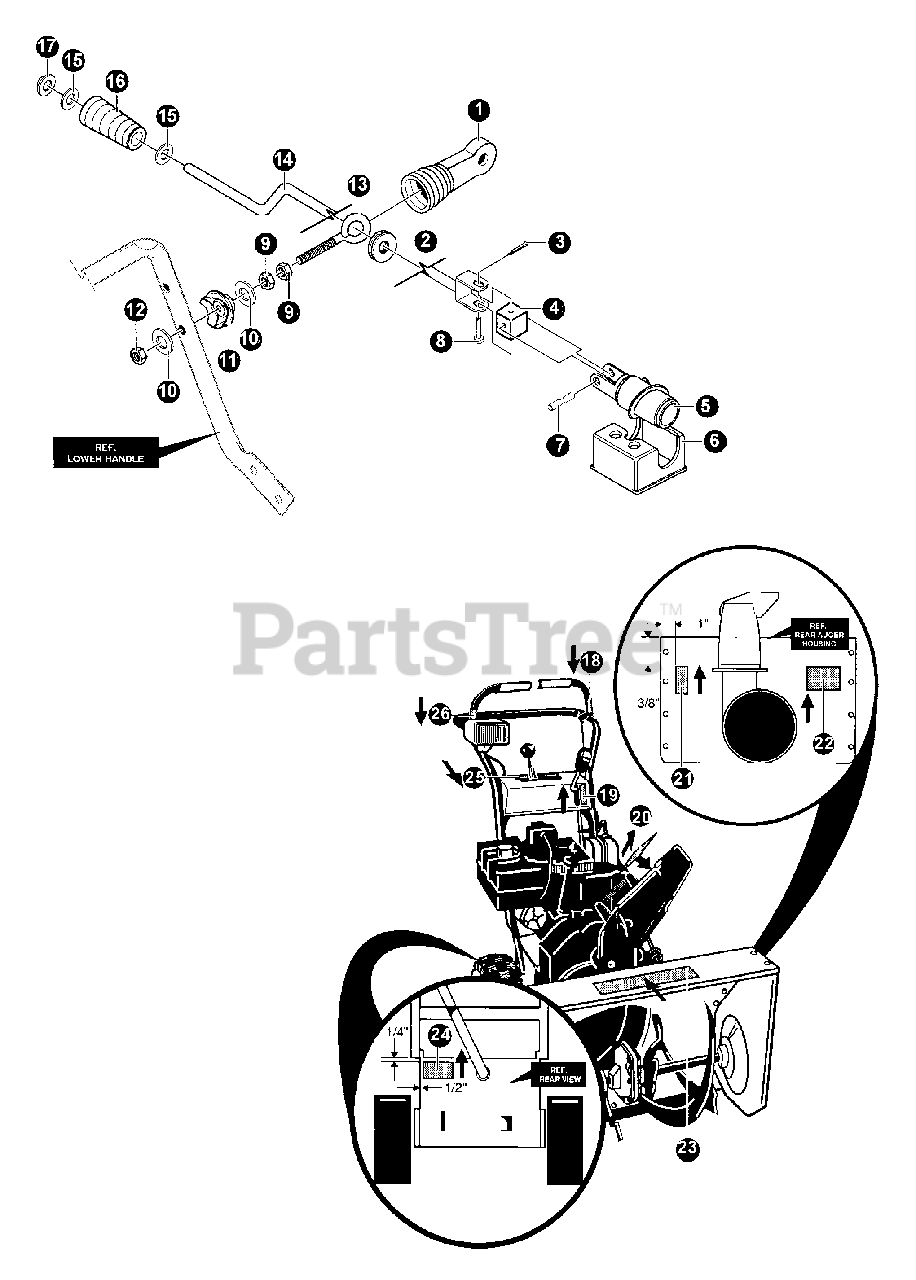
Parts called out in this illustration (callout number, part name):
1	BOOT, EYEBOLT CHUTE
2	GROMMET, EYE BOLT
3	PIN, COTTER
4	BLOCK, UNIV PIV
5	GEAR, WORM
6	BRACKET, WORM MTG
7	PIN, U-JOINT
8	PIN, CLEVIS
9	NUT, 3/8"-16
10	WASHER
11	ADAPTER, BOOT
12	NUT, 3/8"-16
13	BOLT - 3/8-16×5 -- EYE
14	CRANK ASSY
15	WASHER, FLAT
16	HANDLE, CHUTE CRANK
17	E-RING
18	LABEL - TRACTION DRIVE ENGAGE
19	LABEL - REMOTE CHUTE
20	LABEL - DANGER
21	LABEL - DANGER
22	LABEL - DANGER
23	LABEL - ECHO
25	LABEL - GEAR SELECTOR
26	LABEL - AUGER DRIVE ENGAGE
